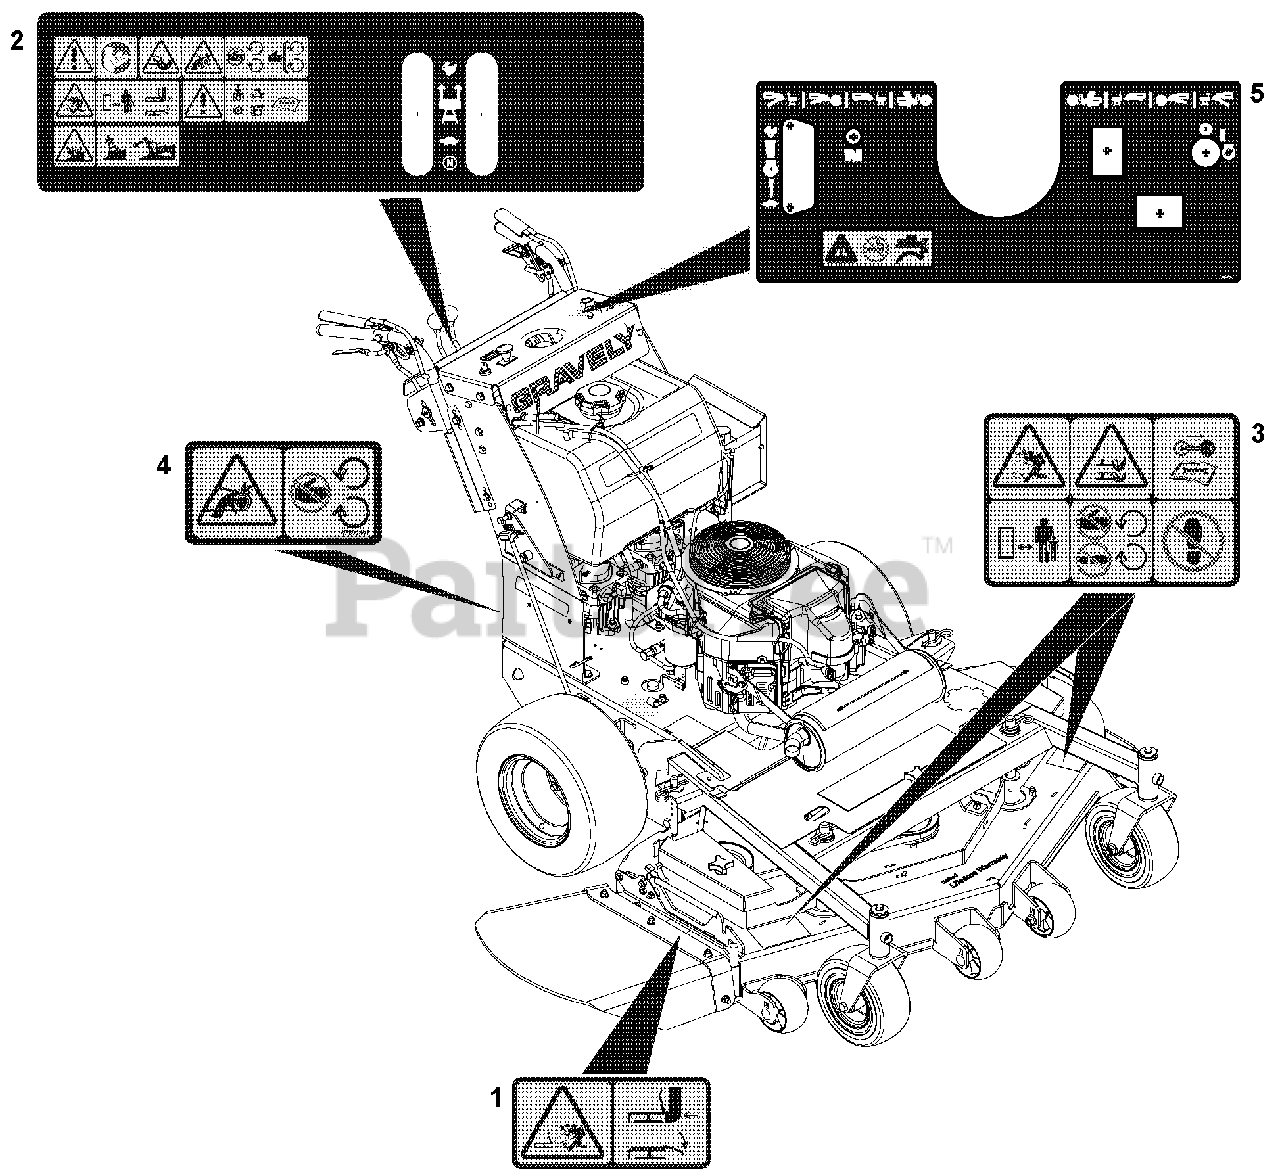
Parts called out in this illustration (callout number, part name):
1	Decal, Safety- Deck Guarding
2	Decal, Lower Console PG CE
3	Decal, Safety- Mower Deck (988323)
3	Decal, Safety- Mower Deck (988324, 325)
4	Decal, Safety Guarding
5	Decal, Gravely Console
